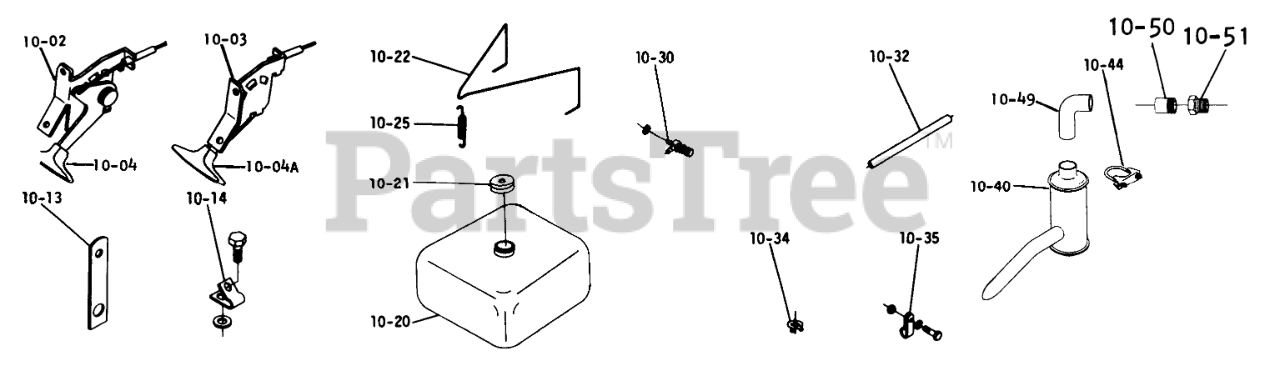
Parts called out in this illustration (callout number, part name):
10-02	Choke Control
10-03	THROTTLE CONTROL
10-03	CONTROL-THROTTLE
10-04	KNOB-CHOKE
10-04A	KNOB-THROTTLE
10-13	Strap
10-14	THROTTLE CONTROL CLP
10-20	Bushing
10-21	Cap
10-22	HOLD DOWN WIRE
10-25	CLUTCH SPRING
10-30	VALVE-FUEL
10-32	Fuel Hose
10-34	Clamp
10-35	CLAMP-HOSE
10-40	MUFFLER
10-44	ASSY-MUFFLER CLAMP
10-49	MUFFLER INLET TUBE
10-50	NIPPLE
10-51	REDUCER 1 1/4-1
